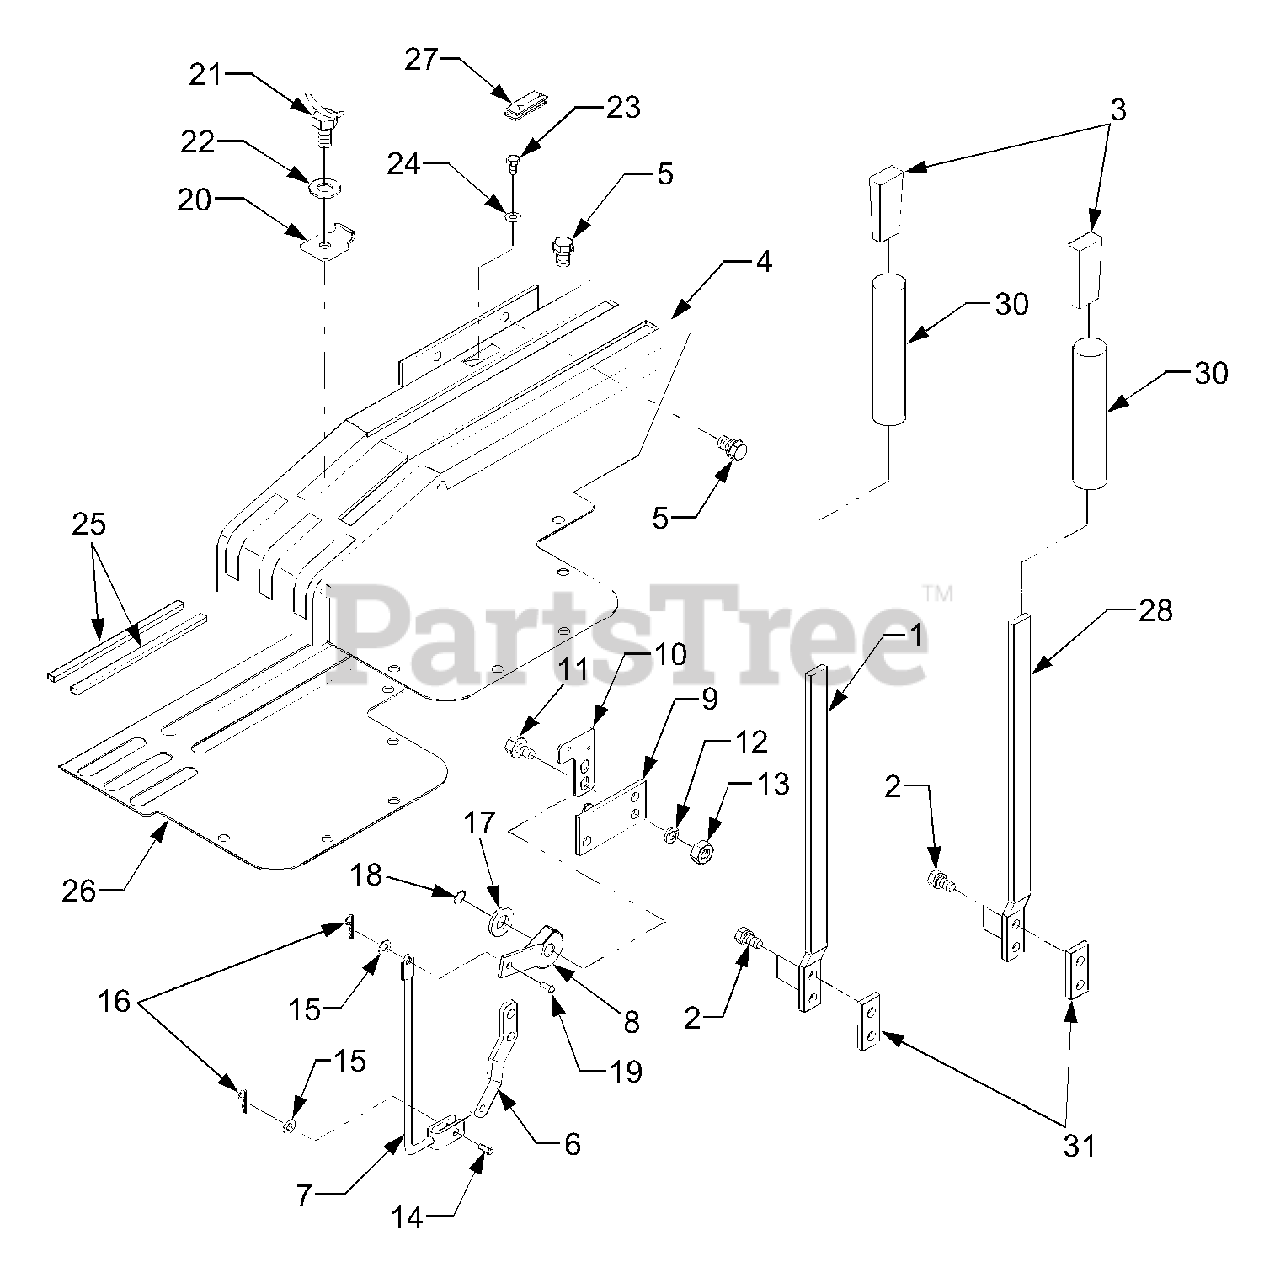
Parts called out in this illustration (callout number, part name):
4	Guide, Hydraulic Lever
6	Lever 1(Switch)
12	Washer, Spring
15	Washer, Plain
17	Washer, Plain
22	Washer, Plain
24	Washer, Plain
28	Lever, Position Control
